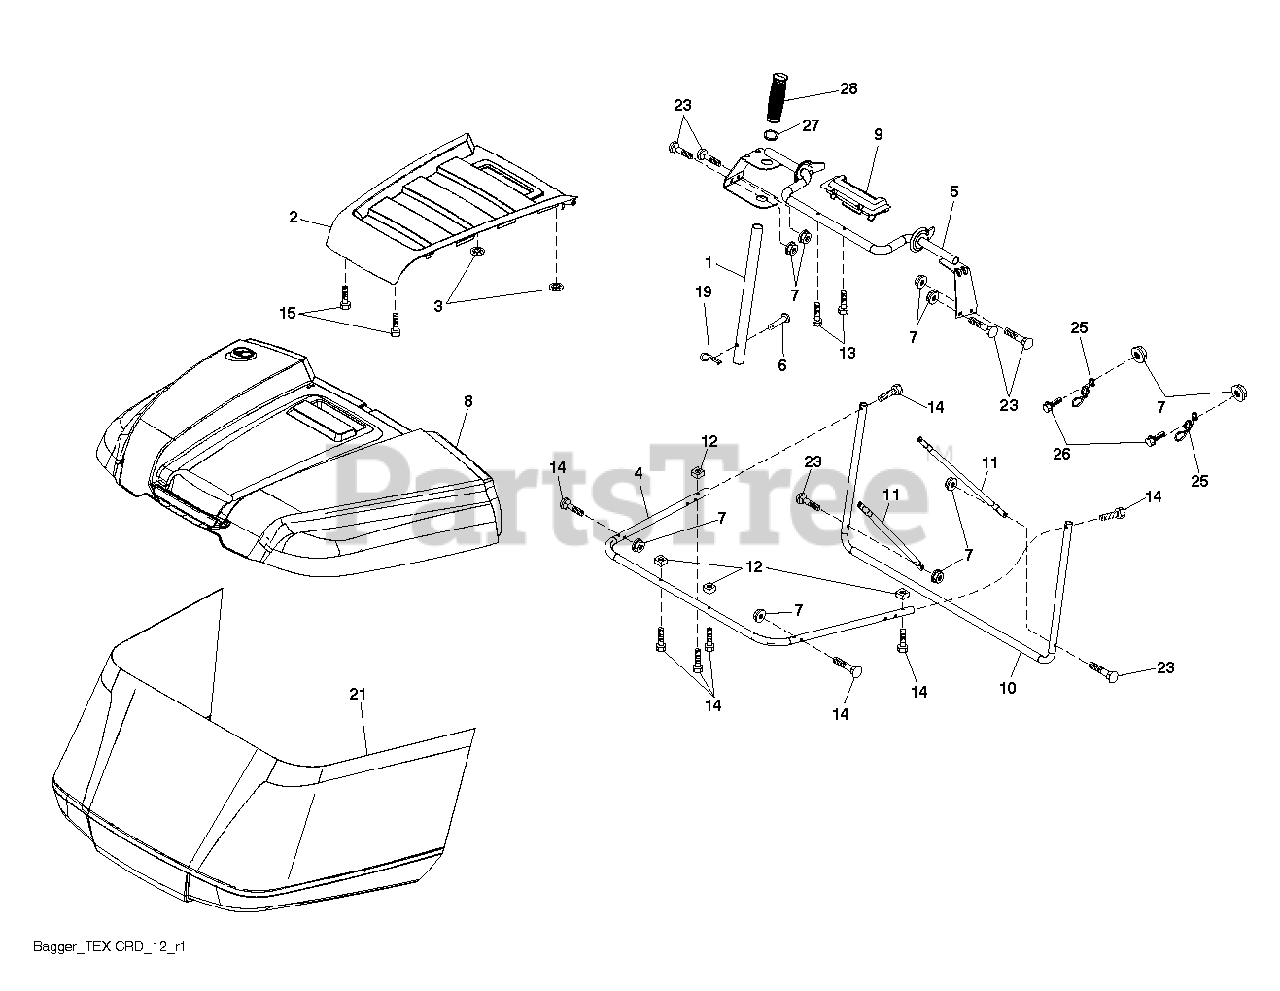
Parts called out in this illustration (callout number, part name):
1	TUBE.HANDLE.BAGGER.CRD/SRD.BLA
2	APPLIQUE.TOP.BAG.SRD.ORANGE
3	NUT.PUSH.156
4	SUBASM.TOP.TUBE.TEX.CRD
5	FRAME.ASM.TOP.BAGGER.SRD
6	RIVET,DRILLED
7	NUT T
8	BAGGER.TOP.SRD.APPLIQUE
9	INSERT.HANDLE.BAGGER.(2 2)
10	FRAME FRAME.FRONT.TEX.CRD
11	BRACE BRACE SIDE TUBE
12	NUT.SQUARE.1/4
13	SCREW.1/4X1.150.HXWSH
14	BOLT.SHOULDER.HX.WSH.1/4X1.150
15	SCREW,#8.FLAT.HEAD.DRILL.TIP
19	PIN.COTTER.5/16.BOW TI
21	BAG SUBASM. TEX CRD GEN 2 HUSQ
25	SPRING.LATCH.BAGGER.SRD
26	SCREW HEX CRT
27	RB GROMMET.RUBBER.SRD
28	GRIP.HANDLE.BLACK
